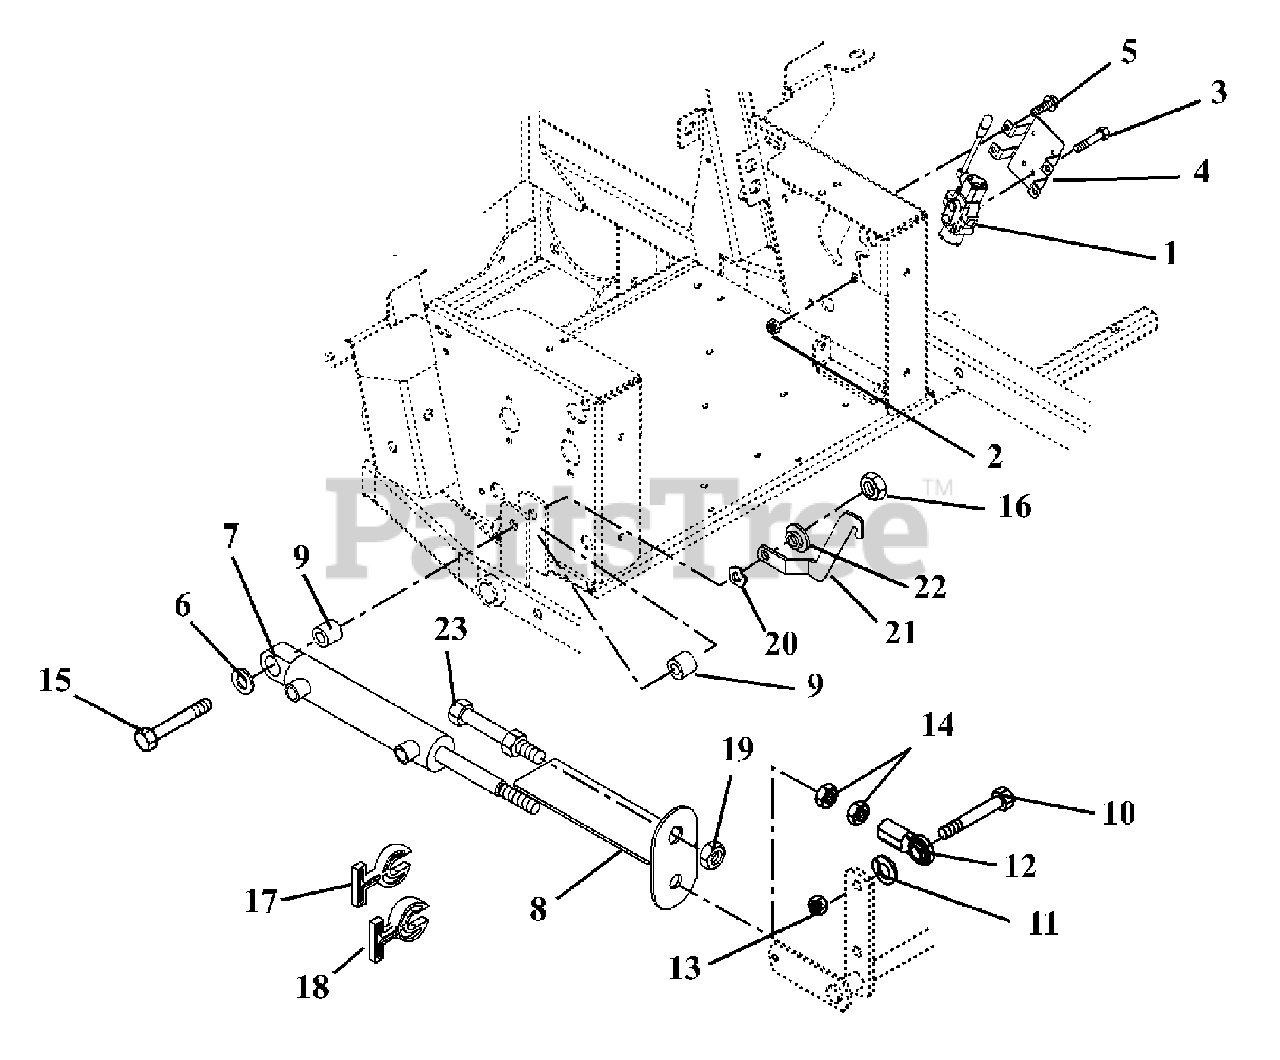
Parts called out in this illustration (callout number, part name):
1	VALVE, HYDRAULIC-BONDIOLI
2	@NUT-LK-TOP-FLG .31-18 YWZC
3	@BLT-HEX .31-18X2.50 GR5 YWZC
4	VALVE MOUNTING BRACKET - BLACK
5	@SCR-TAP .38-16X.50 HWH TR YWZ
6	WSHR-FL-STL .515X1.625X.250 YZ
7	CYLINDER, LIFT
8	CUT INDICATOR/GUARD - BLACK
9	BUSHING, .516X1.000X1.050 LG
10	BLT-HEX .62-11X2.25 YWZC GR8
11	@WSHR-LK .62X.156 REG YWZC
12	ROD END, 5/8 RH - FEMALE
13	@NUT-LK-CTR .62-11 YWZC
14	NUT-JAM .625-18 YWZC
15	@BLT-HEX .50-13X3.75 GR5 YWZC
16	@NUT-LK-TOP-FLG .50-13 YWZC
17	STOP, CYLINDER .34 THK
18	STOP, CYLINDER .680 THK
19	NUT-JAM .75-16 YWZC
20	WASHER-WAVE .760X1.120X.080
21	LATCH, FOOTBOARD HOOK
22	BSHG-FLG .515X.750X.285X1.120
